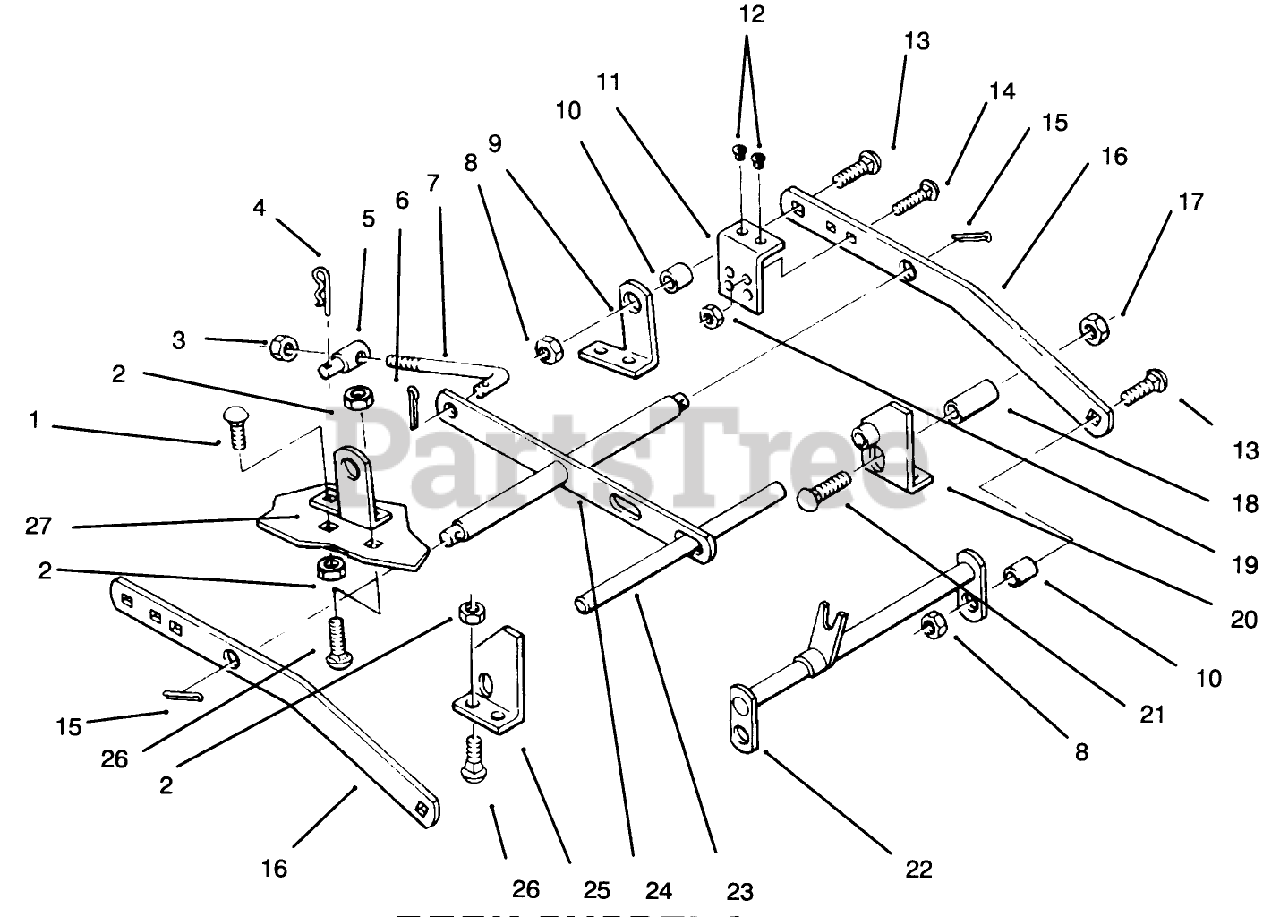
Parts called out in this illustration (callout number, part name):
1	BOLT-CARR
2	NUT-HEX
3	NUT-LOCK, NI
4	Hairpin
5	TRUNNION-LIFT
6	PIN-COTTER
7	ROD-LEVEL ADJUST
8	LOCKNUT-FLANGE
9	LH Rear Bracket
10	SPACER
11	Bumper-Metal
12	BUMPER-RUBBER
13	BOLT-CARR
14	BOLT-CARR
15	PIN-COTTER
16	Bar Draft
17	Nut
19	Nut
20	Front Bracket LH
21	BOLT-CARR
22	Hitch
23	Front Shaft
24	Leveler
25	Front Bracket RH
26	SCREW-CARR
27	Rear Bracket RH
